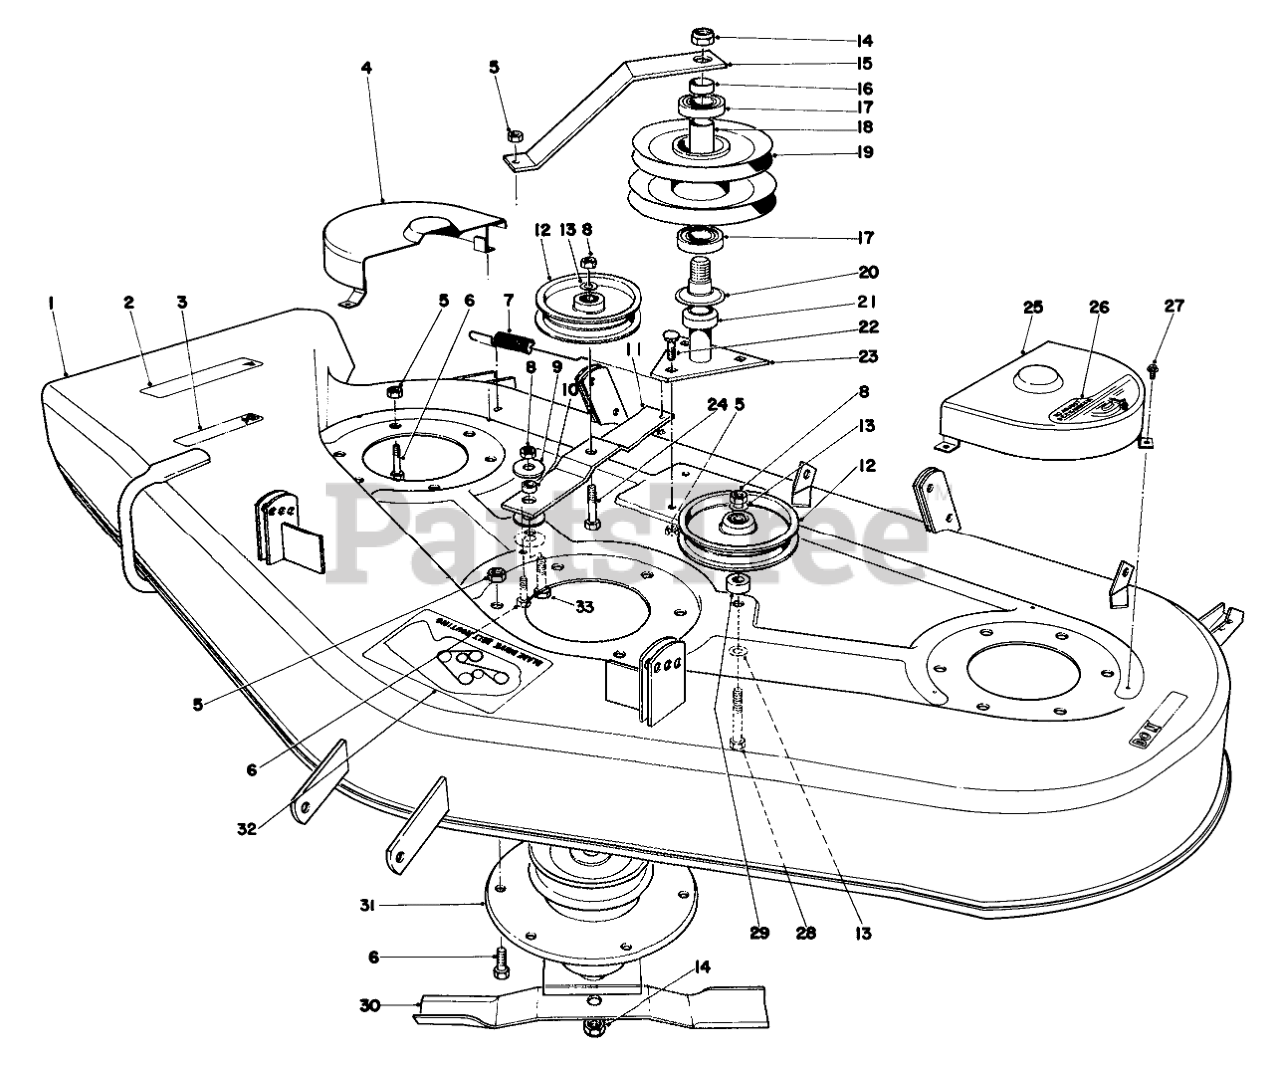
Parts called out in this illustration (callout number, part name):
1	42 IN DECK WA B
2	CAUTION DECAL
3	DECAL-NO STEP
4	RH BELT COVER WA B
5	NUT-LOCK, CONE
6	SCREW-HH
7	EXT SPRING O
8	NUT-LOCK, CONE
9	WASHER
10	IDLER BRKT SPACER
11	Idler Pulley Bracket
12	PULLEY-IDLER
13	WASHER-FLAT
14	NUT-LOCK, NI
15	Support Spindle
16	SPACER
17	BEARING
18	SPACER
19	Pulley & Bearing Assembly
20	DUST COVER
21	SPACER
22	BOLT-CARR
23	SHAFT SADDLE ASM
24	SCREW-HH
25	LH BELT COVER WA B
26	WHEEL ADJ DECAL
27	SCREW-HWHTF
28	SCREW-HH
29	SPACER O
30	Blade
31	Spindle Assembly
32	Decal Belt Routing
33	SCREW-HH
